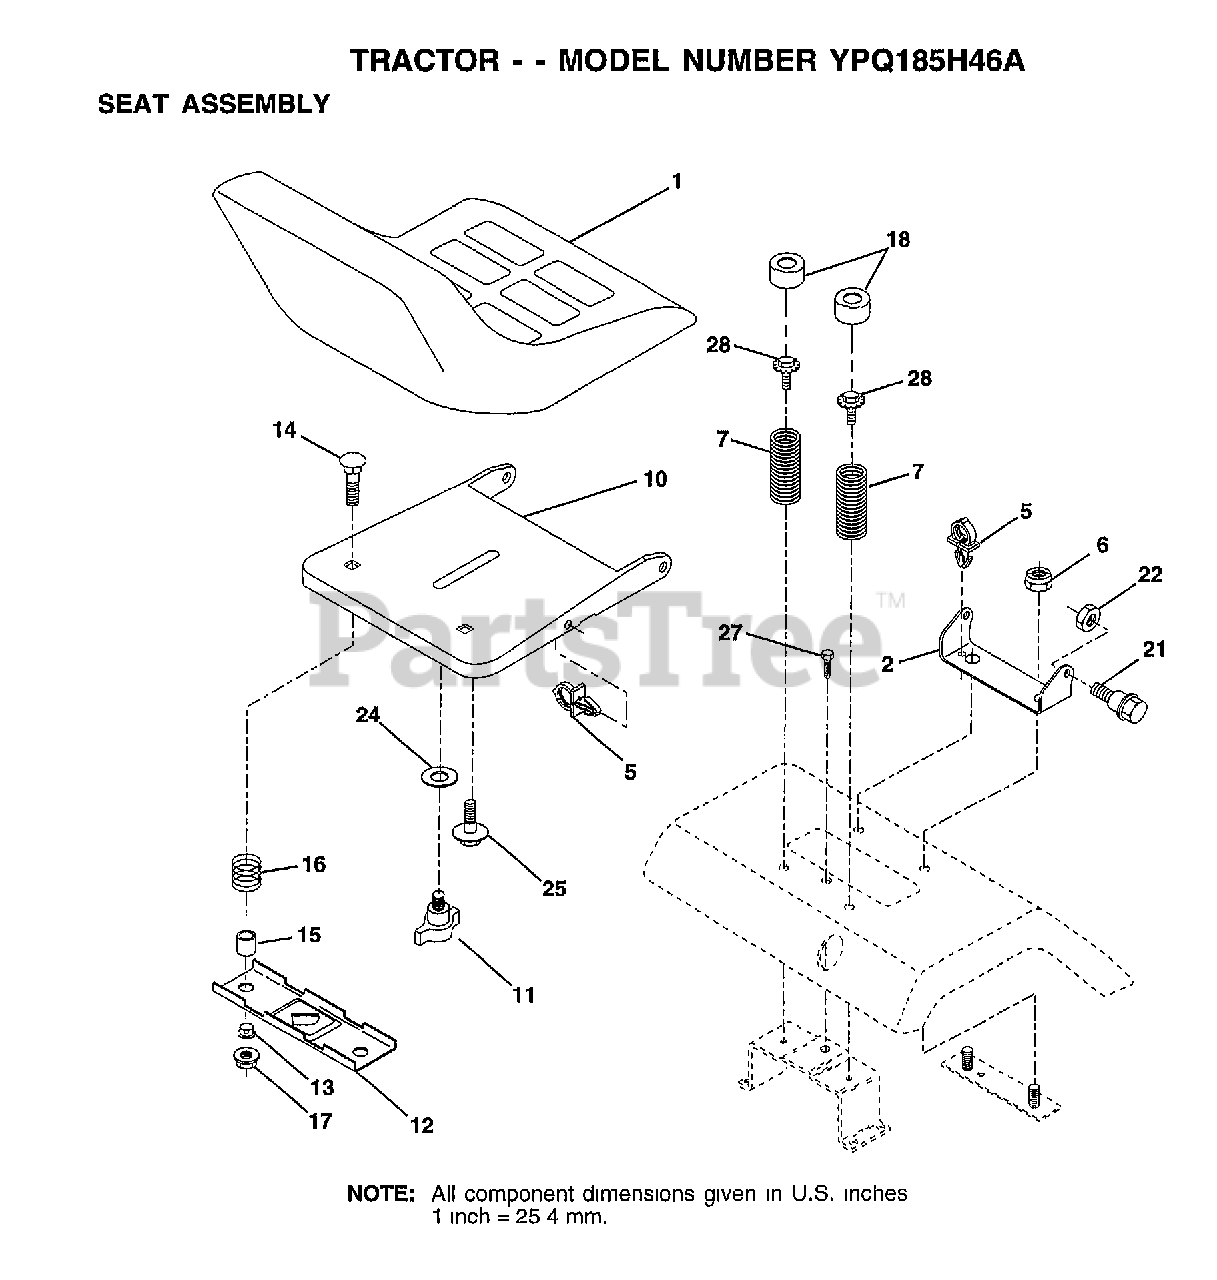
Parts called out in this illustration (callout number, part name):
1	SEAT.2500/1516.BK
2	BRACKET PVT SEAT
5	CLIP.PUSH-IN.HING
6	NUT
7	SPRING COMPRESSIO
10	PAN-SEAT
11	KNOB.SEAT.ADJ.WINGNUT
12	BRKT SWITCH
13	BUSHING
14	BOLT-RD HD SQ NK
15	SPACER SPLIT
16	SPRING COMPRESSED
18	CAP SPRING
21	"BOLT,SHOULDER"
22	NUT
24	WASHER
25	"BOLT,SHOULDER"
27	SCREW LT
28	BOLT.5/16-18.UNC
